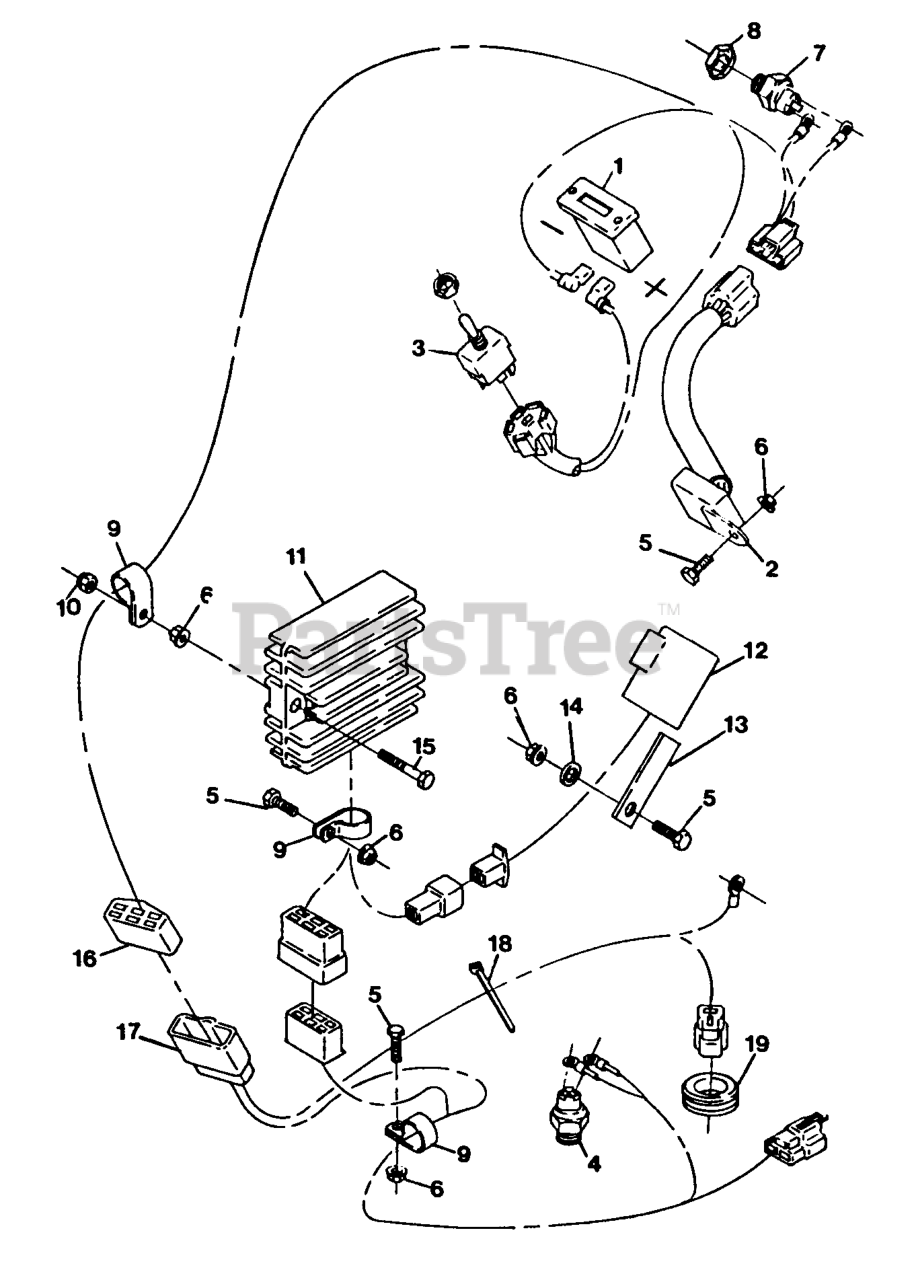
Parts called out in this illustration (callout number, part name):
1	METER-HOUR
3	SWITCH,W/TERM CLIPPD
4	SWITCH-START, NEUTRAL
7	SWITCH,OPERATOR CNTRL
9	CLIP-LOOM
18	TIE-CABLE
19	GROMMET
